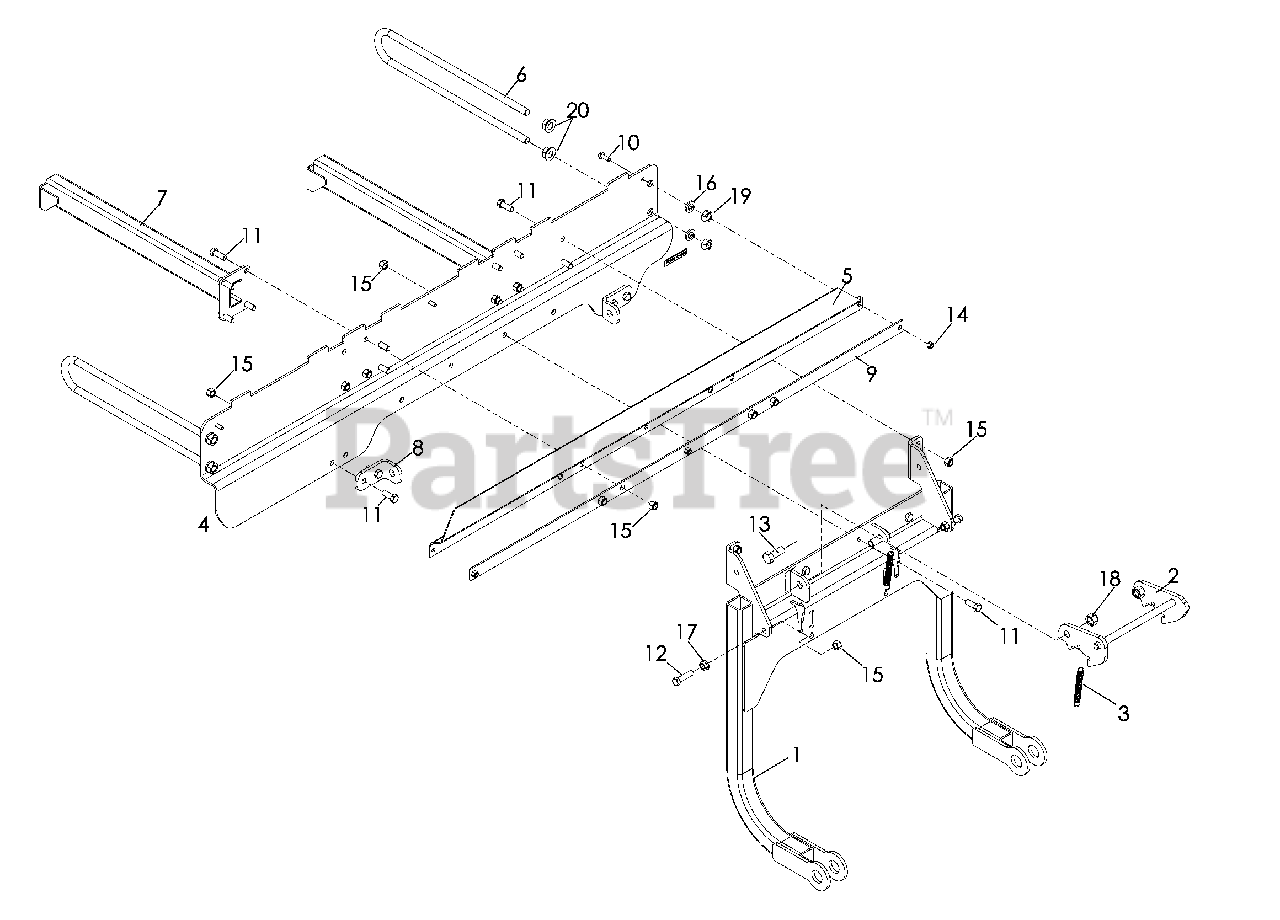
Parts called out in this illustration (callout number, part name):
4	MOUNT Z BRACE
5	SEAL RUBBER
6	SUPPORT, OUTER
7	SUPPORT ARM
8	BRACKET, SUPPORT
9	SEAL STRAP
10	HCS ¼-20 x ¾
11	HCS 3/8-16 x 1
12	HCS 3/8-16 x 1½
13	HCS ½-13 x 1¼
14	NUT ¼-20 NYLOC
15	NUT 3/8-16 NYLOC
17	NUT 3/8-16 WHIZLK
18	NUT ½-13 NYLOC
19	NUT ½ JAM
20	NUT ½-13 WHIZLOCK
